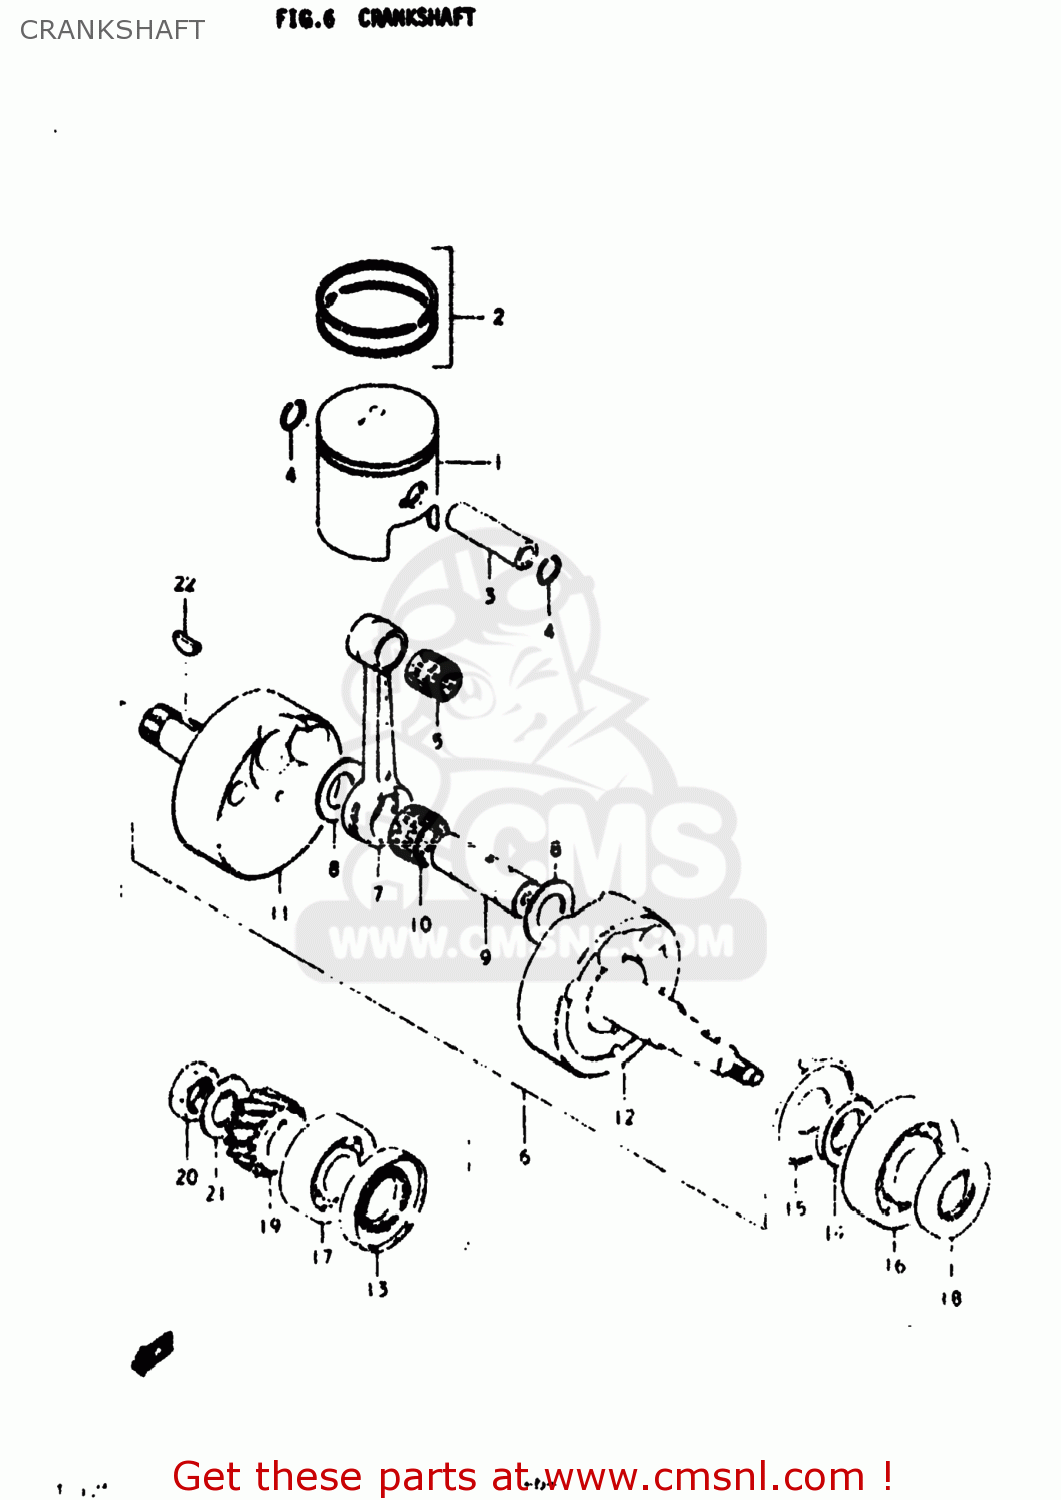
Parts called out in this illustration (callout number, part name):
1	PISTON
2	RING SET,PISTON
3	PIN,PISTON
4	RING,SNAP 14MM
5	BEARING
6	CRANKSHAFT ASSEMBLY
7	CONNECTING ROD
8	WASHER(19X32X1)
9	PIN,CRANK
10	BEARING
11	CRANKSHAFT
12	CRANKSHAFT,LEFT
13	SEAL,OIL(26X52X8)
14	SPACER
15	PLATE,CRANKSHAFT OIL GUIDE
16	BEARING(25X62X17)
17	BEARING
18	OIL SEAL
19	GEAR,PRIMARY DRIVE
20	NUT
21	WASHER
22	KEY
